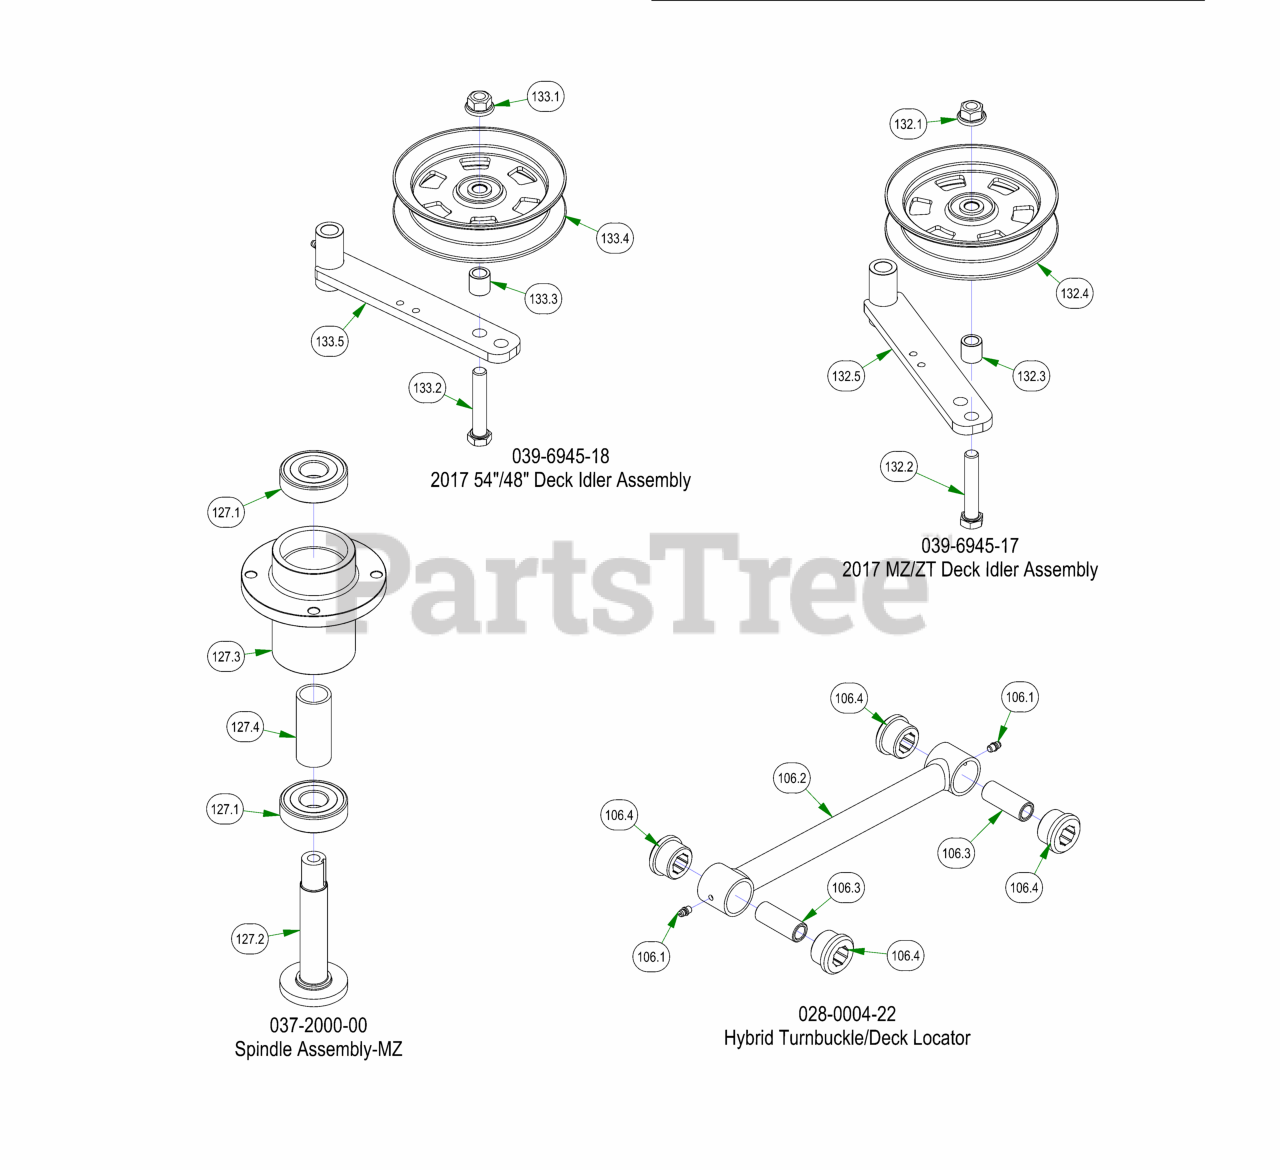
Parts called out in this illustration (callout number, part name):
83	1/4 USS FLAT WASHER (3/4 OD) ZINC
91	ZT Tire and Rim Assembly 22 x 11 - 10
106	Hybrid Turnbuckle/Deck Locator
106.1	1/4-28 Grease Fitting
106.2	2022 Isolator Turnbuckle Body
106.3	2018 Maverick Bushing Sleeve
106.4	2018 Maverick Bushing
127	Spindle Assembly-MZ
127.1	Spindle Bearing
127.2	Spindle Shaft
127.3	Spindle Housing
127.4	Spindle Spacer-Component
132	2017 MZ/ZT Deck Idler Assembly
132.1	1/2-13 NYLON INSERT FLANGE LOCKNUT ZINC
132.2	1/2-13 X 2-3/4 HEX CAP SCREW (GR.5) ZINC
132.3	.51 ID X .75 OD X .75 LGTH SOLID SPACER ZINC
132.4	5" Idler Pully
132.5	Deck Idler
133	2017 54"/48" Deck Idler Assembly
133.1	1/2-13 NYLON INSERT FLANGE LOCKNUT ZINC
133.2	1/2-13 X 2-3/4 HEX CAP SCREW (GR.5) ZINC
133.3	.51 ID X .75 OD X .75 LGTH SOLID SPACER ZINC
133.4	5" Idler Pully
133.5	Deck Idler
